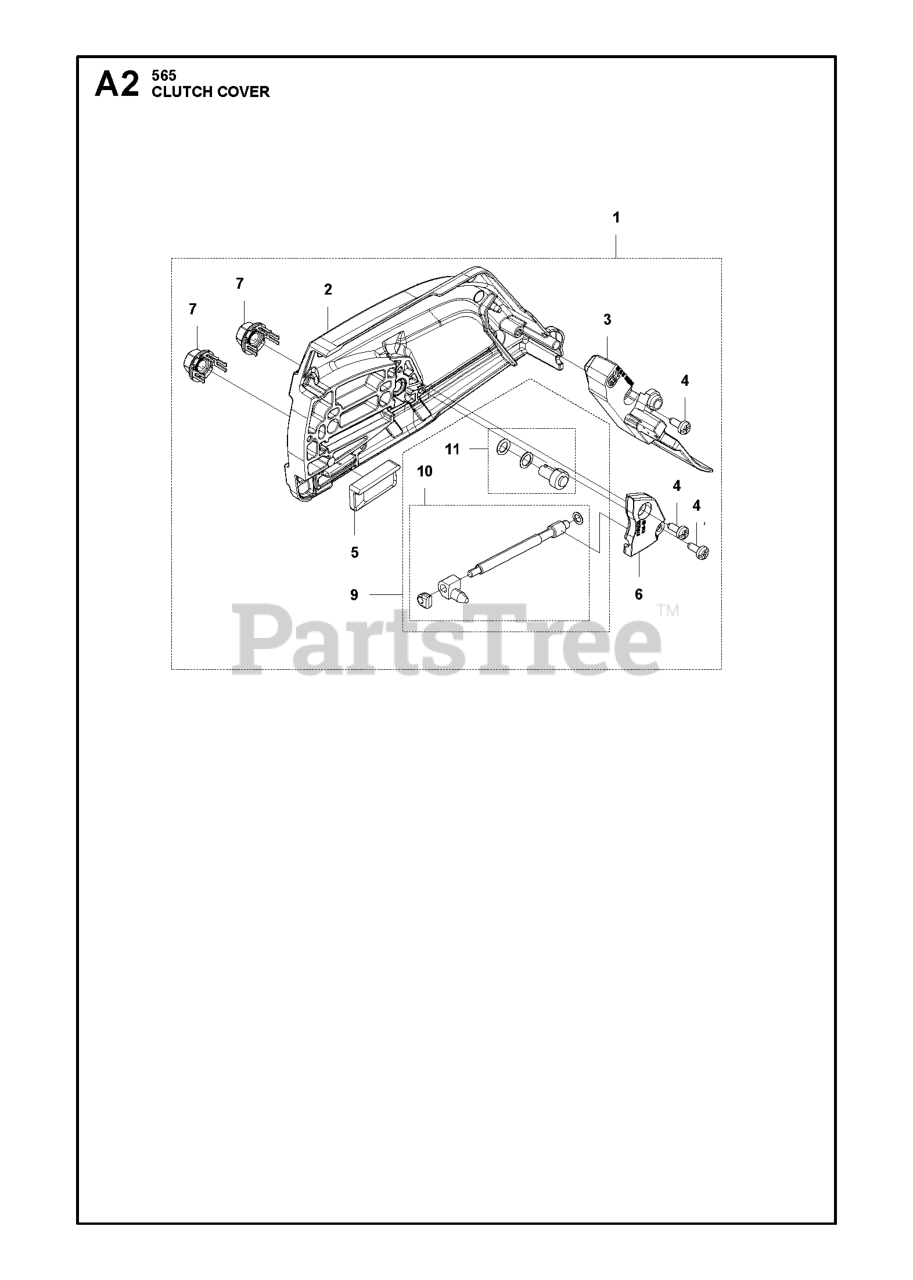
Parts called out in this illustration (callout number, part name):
1	CLUTCH COVER ASSY GREY SPARE
2	CLUTCH COVER
3	CHIP GUARD
5	CHAIN GUIDE
6	COVER WORM SCREW
7	NUT RETAINER ASSY
9	CHAIN TENSIONER KIT H565/H572
10	WORM SCREW KIT H565/H572
11	WORM WHEEL KIT H565/H572
